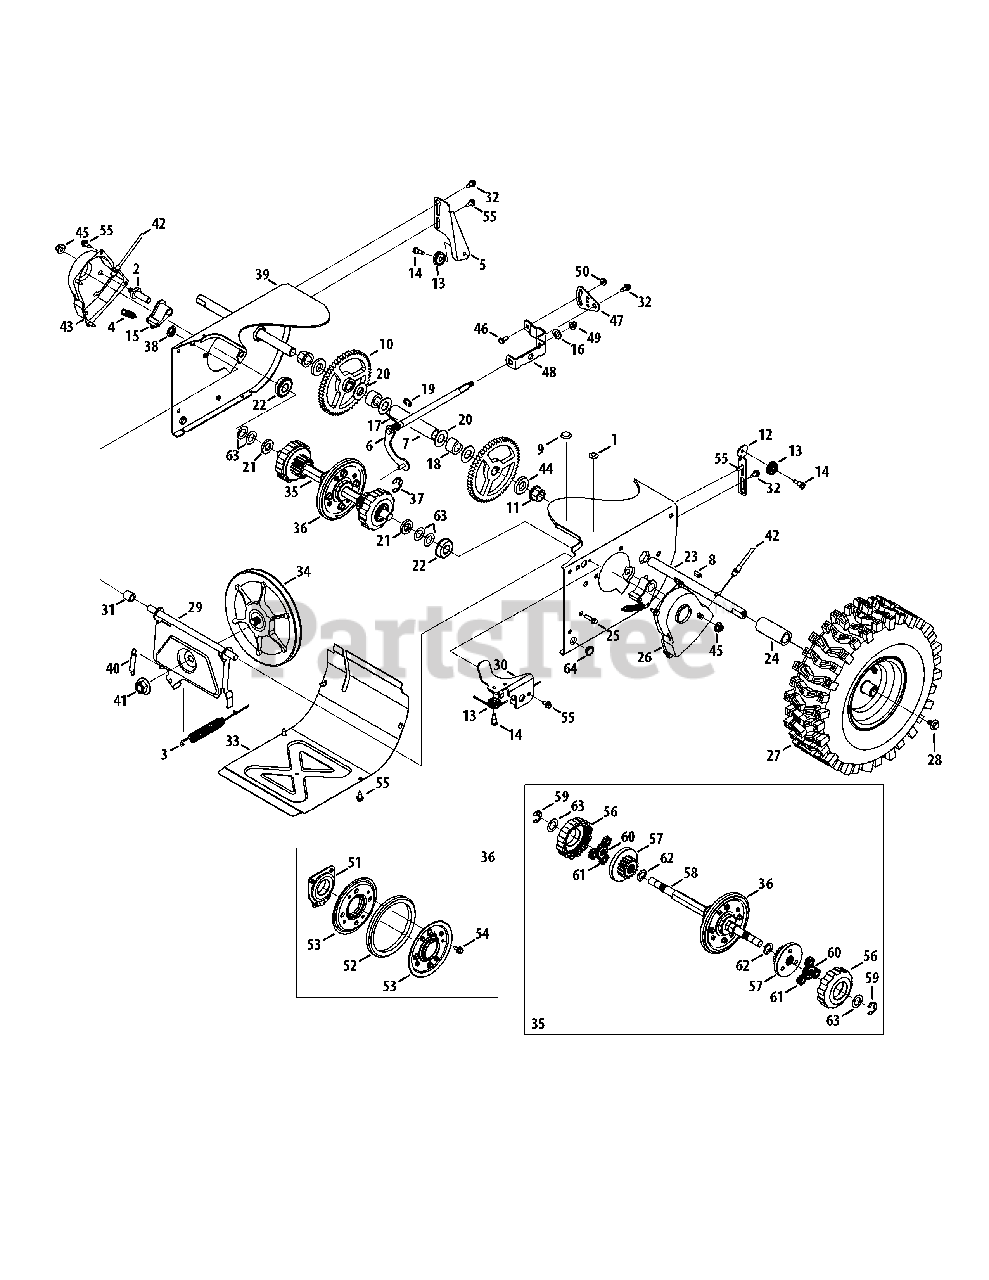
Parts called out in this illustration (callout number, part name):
1	Plug, 3/8 ID
2	Actuator Shaft
3	Drive Clutch Cable
4	Extension Spring
5	Drive Clutch Cable Guide Bracket
6	Shift Rod Assembly
7	Axle Support Tube
8	Hi Pro Key
9	Plug, 1/2 ID
10	Gear, 56T
11	Hex Flange Bearing
12	Auger Clutch Cable Guide Bracket
13	Cable Roller
14	C Screw, 1/4-28 x 0.375
15	Dogg Assembly - LH
15	Dogg Assembly - RH
16	Washer, Flat
17	Torsion Spring, .750 ID x .968 Lg.
18	Spacer
19	E Ring
20	Flat Washer, .76 x 1.49 x .06
21	Spacer
22	Ball Bearing
24	Spacer
25	TT Screw, 1/4-20 x 1.0
26	Shaft Retainer - LH
27	Wheel Complete - LH
27	Wheel Complete - RH
28	Screw, 5/16-24 x 0.75
29	Friction Wheel Support Brkt. Assy.
30	Auger Cable Guide Bracket
31	Spacer
32	Shoulder Screw
33	Frame Cover
34	Friction Wheel Disc Assembly
35	Drive Shaft Assembly
36	Friction Wheel Assembly
37	Retainer Ring
38	Speed Nut
39	Wheel Drive Frame
40	Extension Spring
41	Flange Nut, 5/8-18
42	Steering Cable
43	Shaft Retainer - RH
44	Axle Spacer
45	Flange Lock Nut, 3/8-16
46	Hex Screw, 1/4-20 x .620
47	Speed Selector Pivot Bracket
48	Speed Selector Shift Bracket
49	Flange Lock Nut, 5/16-18
50	Flange Lock Nut, 1/4-20
51	Friction Wheel Bearing Assembly
52	Friction Wheel
53	Friction Plate
54	Screw, 5/16-18 x .750
55	AB Screw, 1/4-20 x 0.625
56	Gear Assembly, Plantry Ring
57	Carrier Assembly, Plantry Ring
58	Shaft, Strbl Drv Hex, .812
59	E-Ring
60	Gear, Sun, 18T
61	Gear, 12T
62	Washer, Thrust, .75 x 1.25 x .03
63	Washer, Flat, .67 x 1.174 x .02
